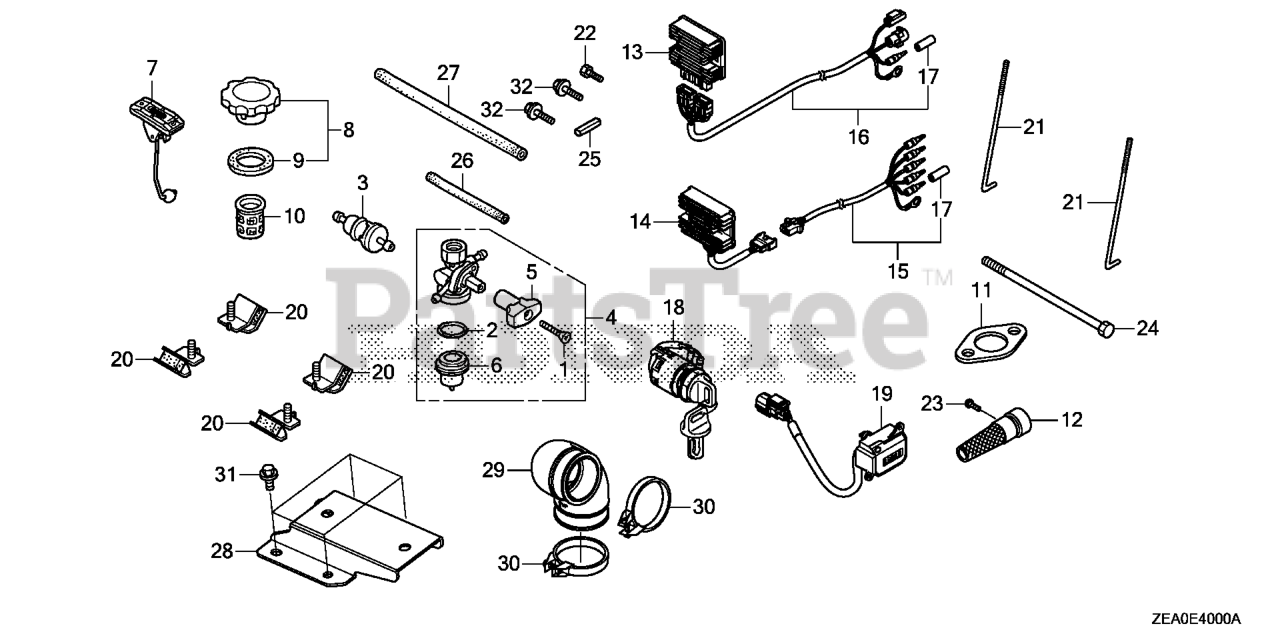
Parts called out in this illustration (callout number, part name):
11	GASKET, EX. PIPE
14	RECTIFIER ASSY., REGULATOR (17A)
15	SUB-WIRE HARNESS ASSY.
17	PLUG, CONNECTOR (OUTER) (ENGINE NO.)
